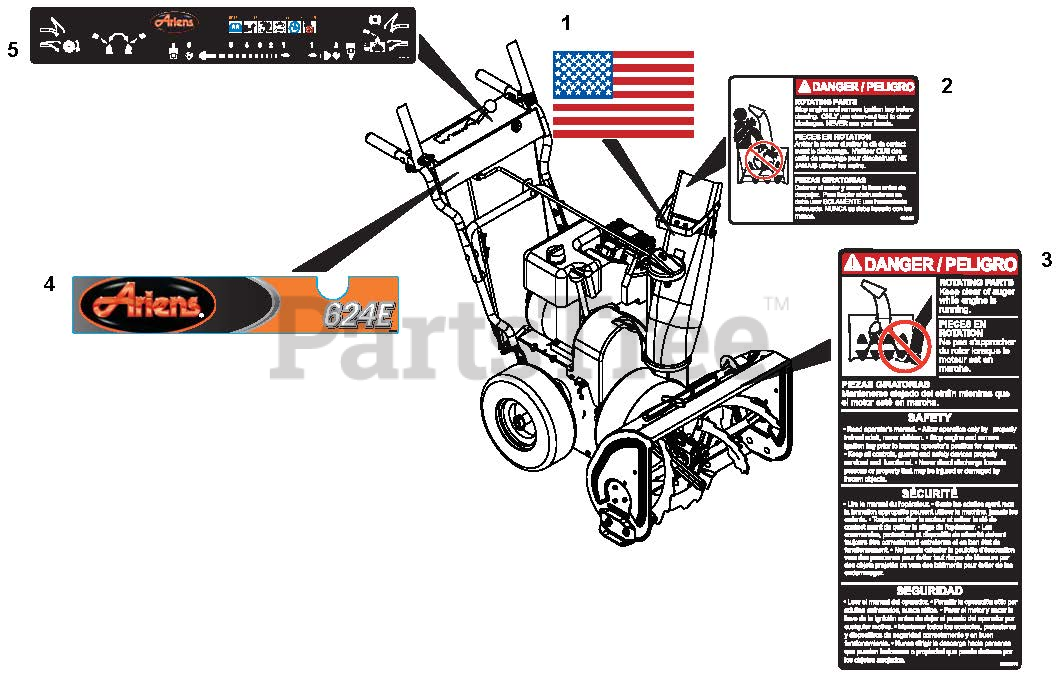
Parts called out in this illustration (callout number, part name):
1	DECAL, AMERICAN FLAG
2	DECAL, DANGER - ROT. PARTS
3	DECAL, DANGER
4	DECAL, DASH - 624E
4	DECAL, DASH - 520E
4	DECAL, DASH - 724E
5	DECAL, CONTROL, COMPACT/DELUXE
